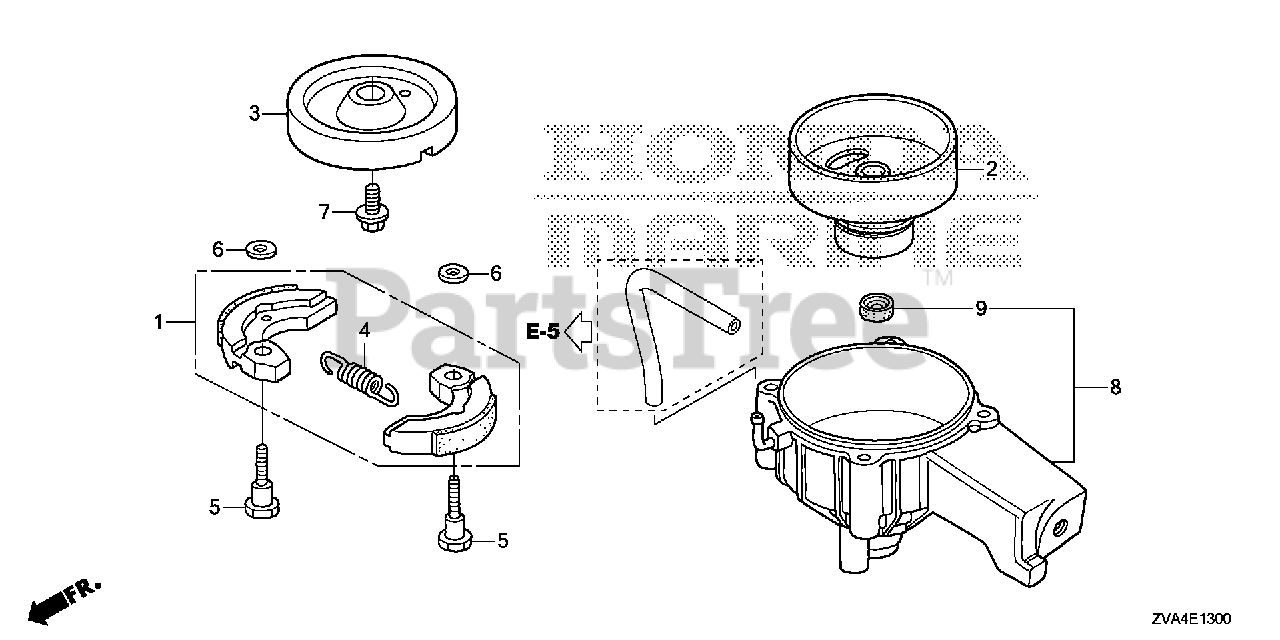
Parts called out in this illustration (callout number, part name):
1	CLUTCH ASSY.
2	CLUTCH OUTER ASSY.
3	STAY, CLUTCH
4	SPRING, CLUTCH SHOE
5	BOLT, CLUTCH (8MM)
6	WASHER, PLAIN (8MM)
7	BOLT, CLUTCH STAY (8MM)
8	HOUSING ASSY., CLUTCH
9	SEAL, WATER (11X21X8)
